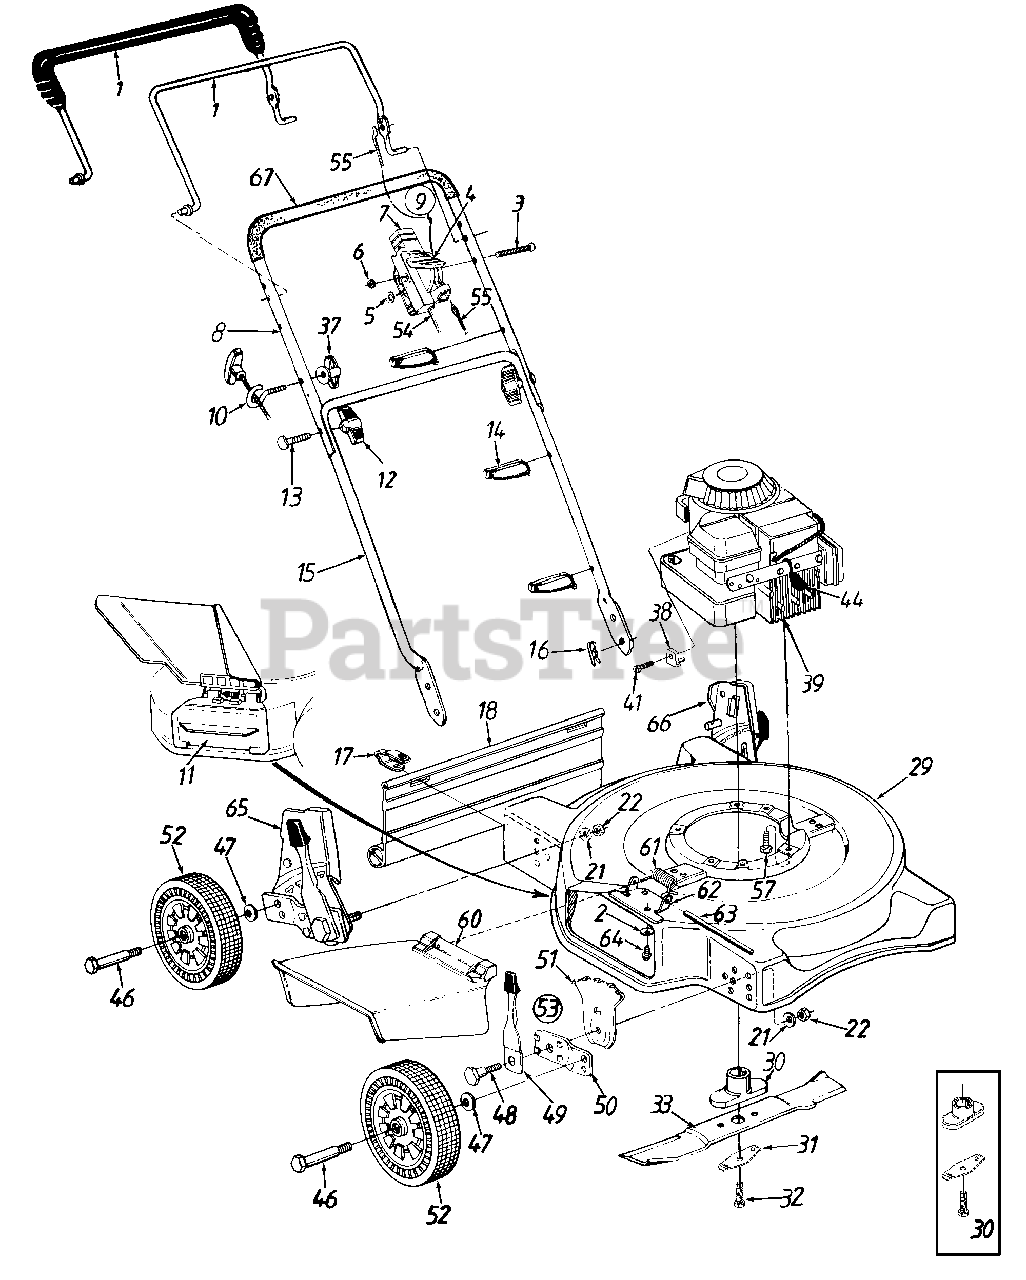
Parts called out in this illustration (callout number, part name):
2	Bell-Wash. 1/4" I.D.
3	Oval C-Sunk Mach. Scr.
4	Throttle Lever
5	Spr. Wash. .66" I.D.
6	Hex L-Nut 1/4-20 Thd.
7	Throttle Body
10	Rope Guide
11	Mulching Plug
12	Hand Knob
13	Curved Hd. Bolt 5/16-18 x 2" Lg.
14	Cable Tie
16	Hairpin Cotter
17	Hinge Clip
18	Rear Flap (20")
21	Bell-Wash. .39" I.D. x 1.38"
22	Hex Nut 3/8-16 Thd.
31	Support, Bell-Blade
32	Hex Bolt 3/8-24 x 1.5" Lg.
33	20" Blade
37	Wing Nut 1/4-20 Thd.
38	Cable Clamp
39	Engine
41	Hex Wash. Hd. Tap Scr. #10-32 x .62 Lg.
44	Spark Plug Boot
46	Axle Bolt
47	Bell-Wash. .400" I.D. x .88"
48	Shld. Bolt .50" Dia. x .357"
49	Spring Lever Ass'y. w/Knob
51	Height Adj. Plate
52	Wheel Assy Comp. (8") Wheels w/o Bearings Grey - Bar Tread
52	Wheel Assy Comp. (8") Wheels w/o Bearings Aero Grey P.B. - Bar Tread
52	Wheel Assy Comp. (7") Wheels w/o Bearings White - Diamond Tread
52	Wheel Assy Comp. (8") Wheels w/o Bearings White - Diamond Tread
52	Wheel Assy Comp. (8") Wheels w/o Bearings Grey - Diamond Tread
52	Wheel Assy Comp. (8") Wheels w/o Bearings Grey - S-Wave Tread
52	Wheel Assy Comp. Wheels with Bearings Grey - Link Tread
52	Wheel Assy Comp. Wheels with Bearings Grey - T-Tread
53	Height Adj. Ass'y. Comp.-R.F.
54	Throttle Cable-51"
55	Control Cable-39"
57	Hex L-Wash. Hd. Scr. 3/8-16 x 1.0" Lg.
60	Chute Deflector Ass'y.
61	Torsion Spring
62	Adapter Plate
63	Hinge Pin
64	Hex Self-Tap Scr. 1/4-20 x .5"
67	Foam Grip
